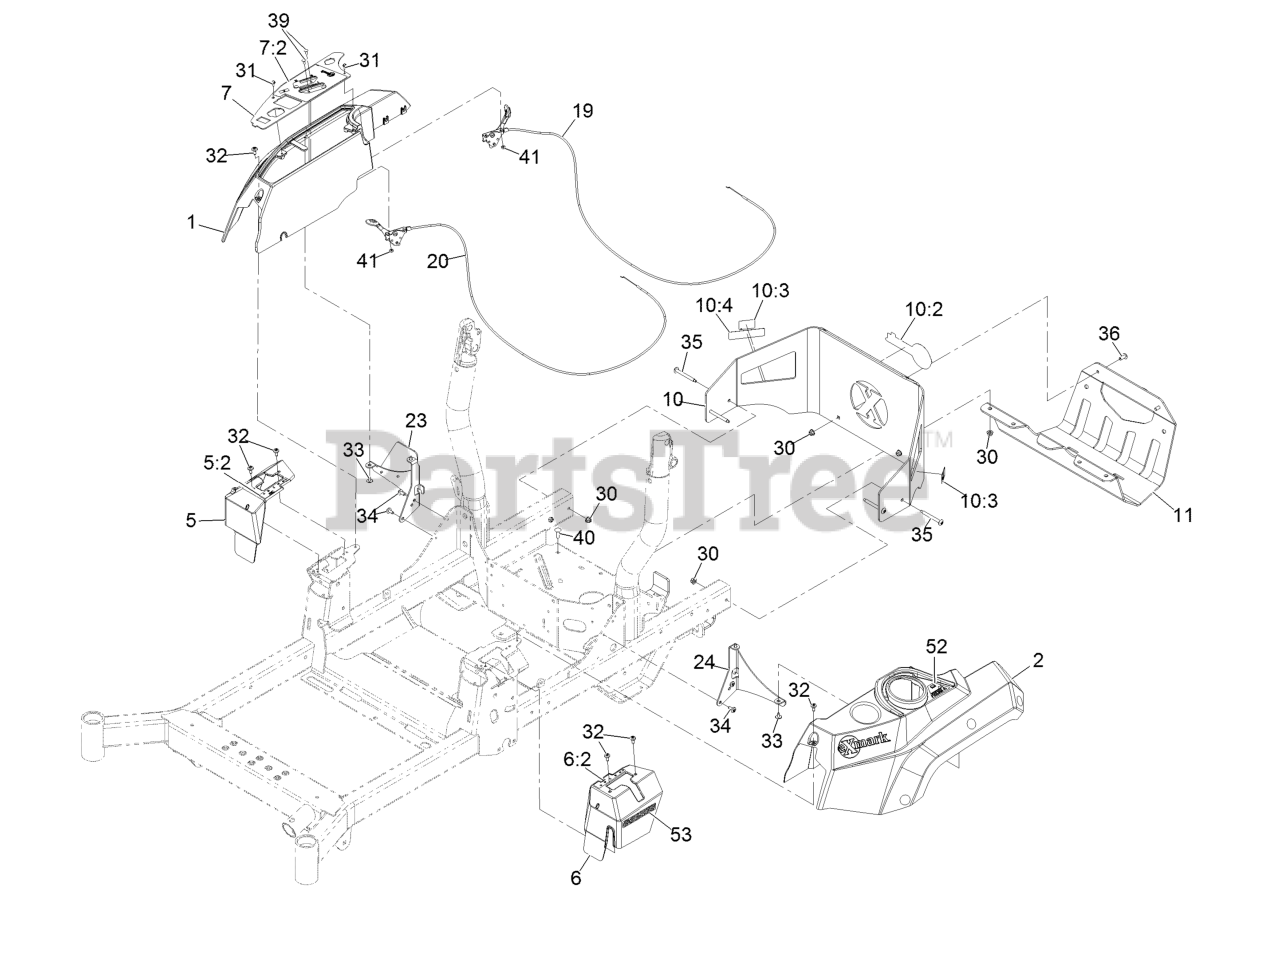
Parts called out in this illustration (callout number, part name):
1	Console, RH
2	Console, LH
5	Cover-Control, Motion (RH)
5:2	Decal-Control, Motion (RH)
6	Cover-Control, Motion (LH)
6:2	Decal-Control, Motion (LH)
7	ASM-Ctrl Panel W/Dcl
7:2	Decal-Control Panel
10	Rear Guard ASM
10:2	Decal-Exmark Logo
10:3	Decal-Warning
10:4	Decal-Arrester, Spark
11	Guard-Muffler
19	Cable-Control, Choke
20	Cable-Control, Throttle
23	Support-Console, RH
24	Bracket-Console, LH
30	Nut-Nyloc 5/16-18 Flg
31	Screw-HWH #10-14 X 1/2
32	Screw-1/4-20 X 1/2 Tf Torx Plus
33	Screw-HWH #10-14 X 1/2 Torx
34	Screw-1/4-20 X .65 Torx Plus
35	Screw-Truss HD 5/16-18 X 2 3/4 Torx Plus
36	Screw-Truss HD 5/16-18 X 3/4 Torx Plus
39	Bolt-Carriage #10-24 X 1/2
40	Bolt-Carriage 5/16-18 X 1 Sp
41	Nut-Nyloc #10-24
52	Decal-Fill, Fuel
53	Decal-E-Series
